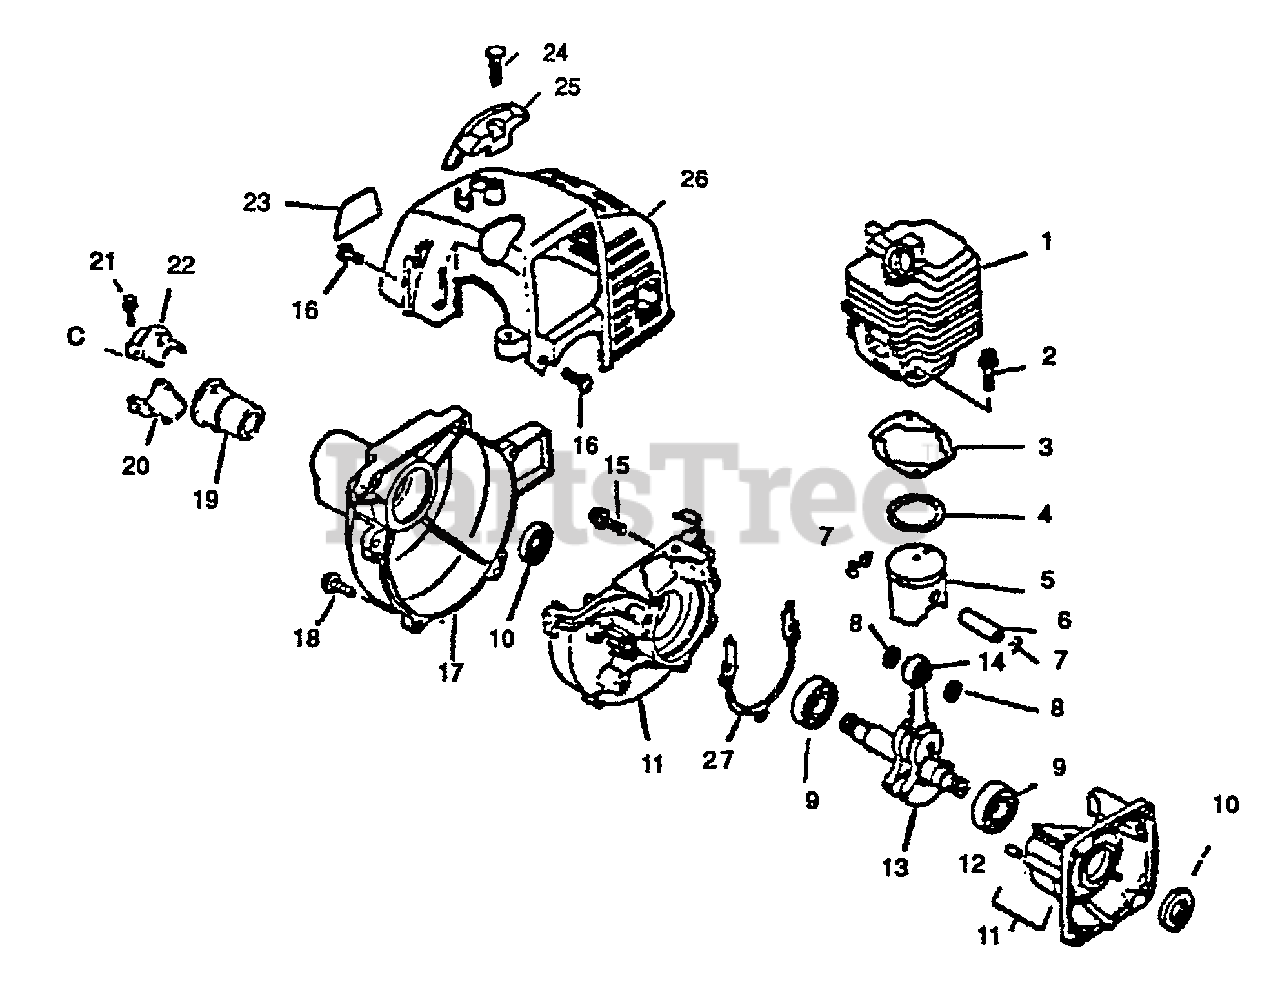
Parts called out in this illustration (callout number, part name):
2	BOLT 5×22
4	RING, PISTON
5	PISTON KIT
6	PIN, PISTON 8
7	RING, SNAP
8	SPACER, PISTON
9	BEARING, BALL 6201
10	SEAL, OIL 12
11	CRANKCASE KIT
12	PIN, LOCATING 4×8
13	CRANKSHAFT ASSY
14	BEARING, NEEDLE
15	SCREW 5×28
16	SCREW 4×12
17	COVER, FAN
18	SCREW 4×16
21	BOLT - 5×25
22	HOLDER, MAIN PIPE - UPPER
23	LABEL, MODEL
24	SCREW 5×16
25	GUARD, TOP - BLACK
26	COVER, ENGINE - GRAY
27	GASKET, CRANKCASE
